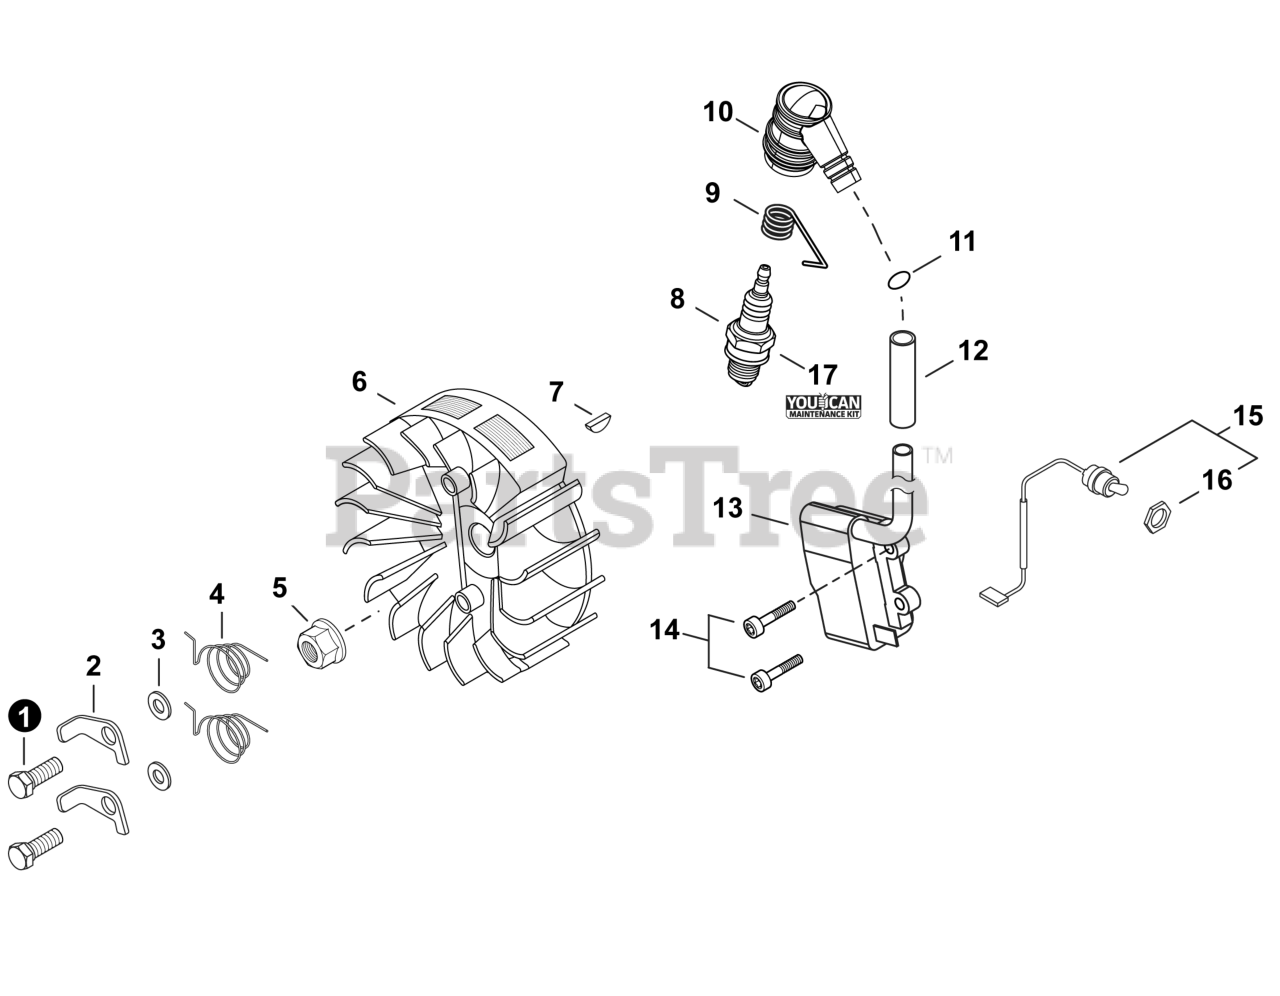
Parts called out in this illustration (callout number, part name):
3	WASHER 6
4	SPRING, TORSION
5	NUT M8×1.0
6	FLYWHEEL
7	KEY, WOODRUFF 3×10
8	SPARK PLUG - BPMR8Y
9	TERMINAL, SPARK PLUG
10	CAP, SPARK PLUG
11	O-RING 7
12	TUBE, INSULATOR
13	COIL, IGNITION
14	BOLT, ADHESIVE M4×20
15	SWITCH ASSY, ON-OFF
17	TUNE-UP KIT - YOUCANT
